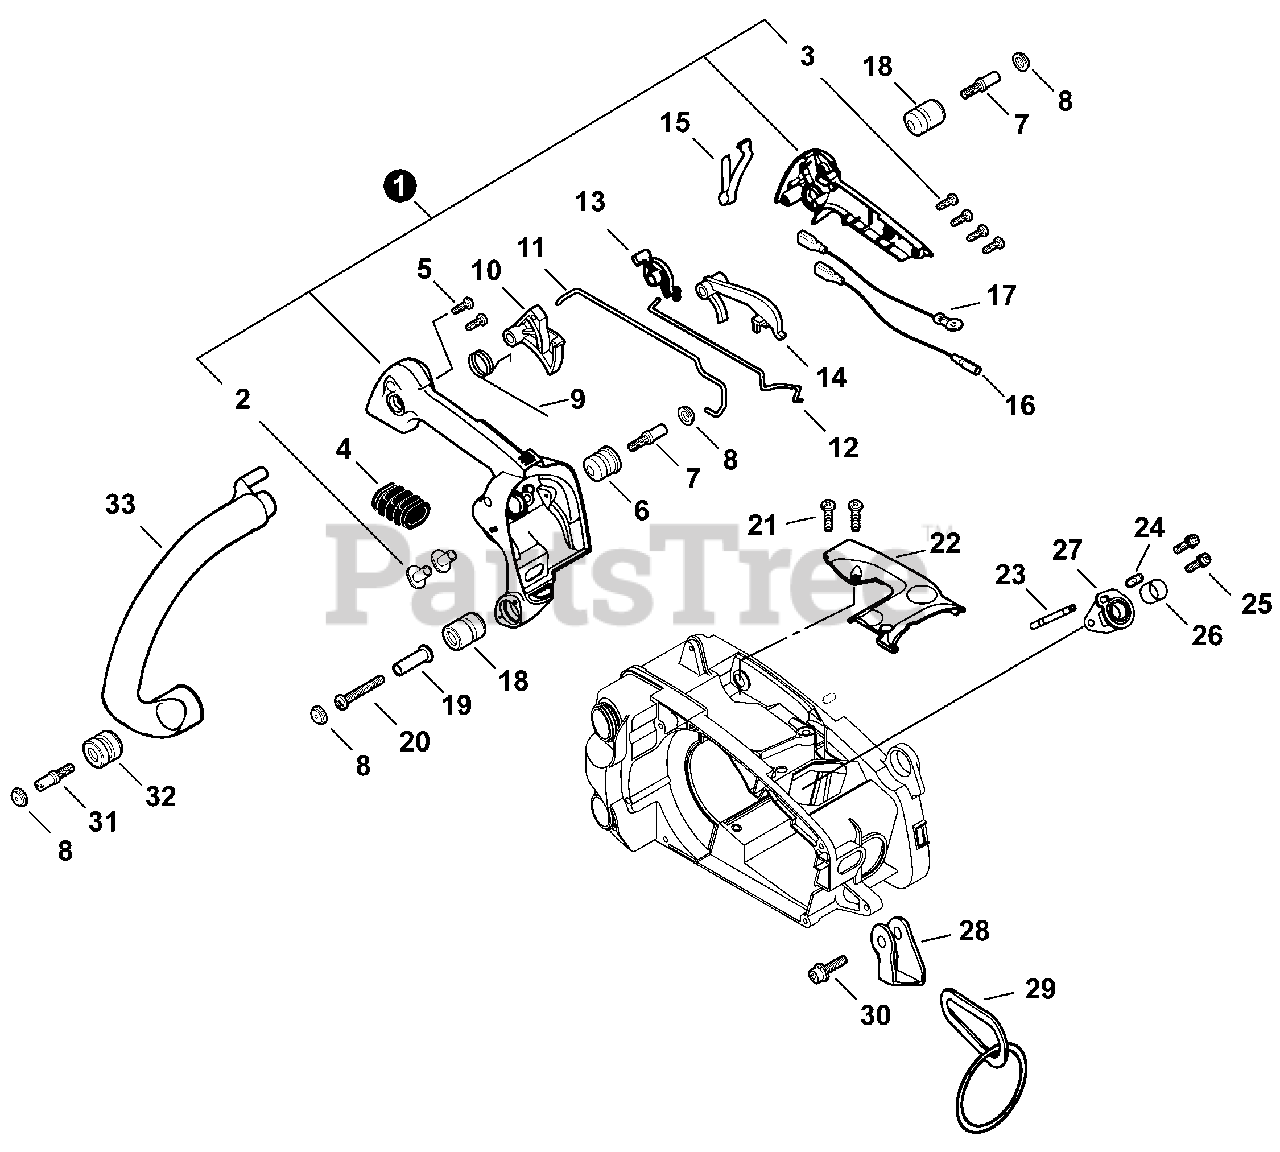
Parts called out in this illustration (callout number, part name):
1	HANDLE KIT, REAR
3	SCREW 4×16
4	BELLOWS, INTAKE
5	SCREW 5×20
6	CUSHION 4
7	BOLT 4×15
8	CAP, CUSHION
9	SPRING, TORSION
10	TRIGGER, THROTTLE
11	ROD, THROTTLE
12	ROD, CHOKE
13	LEVER, CONTROL
14	LOCKOUT, THROTTLE
15	TERMINAL, LEAD
16	LEAD - GROUND
17	LEAD - IGNITION
18	CUSHION
19	COLLAR 4
20	SCREW, TAPPING 4×35
21	SCREW 4×12
22	COVER, DUST - GRAY
23	PIPE, PULSE 3×7×65
24	COLLAR 3.2×6.5
25	SCREW 5×12
26	COLLAR 16
27	BELLOWS, INTAKE
28	BRACKET, HARNESS
29	RING, HARNESS
30	BOLT 4×25
32	CUSHION 5
33	HANDLE, FRONT
